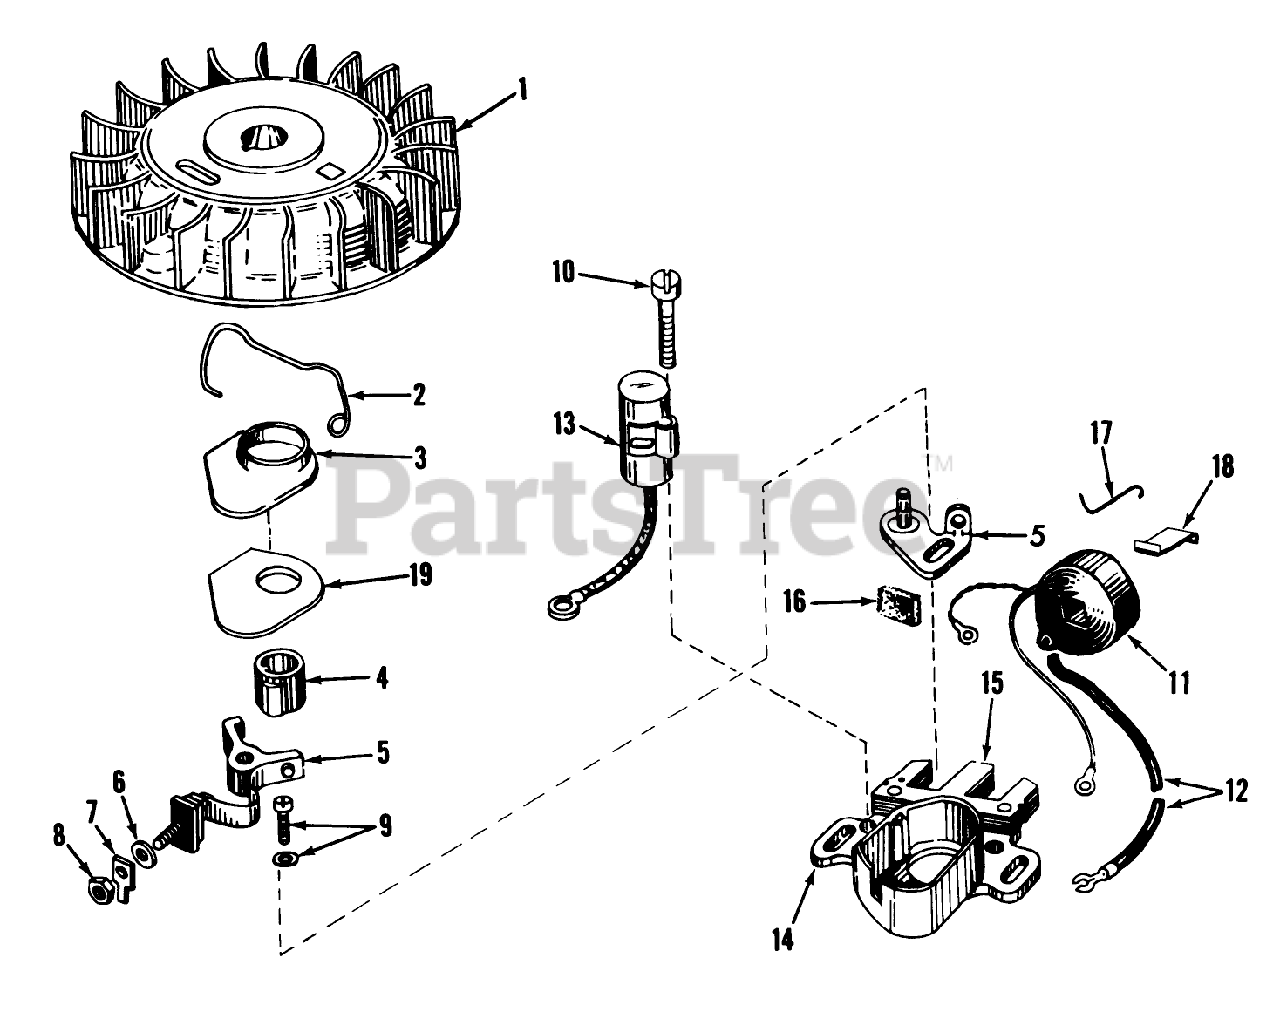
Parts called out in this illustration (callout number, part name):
1	Flywheel
2	Spring Breaker Box
3	Cover, Dust
4	Cam-Breaker
5	Breaker Assy.
6	Washer
7	Terminal
8	DECAL
9	Breaker Screw
10	Condenser Screw
11	Coil Assy. (Incl. No. 12)
12	Wire, Lead
13	Condenser
14	Core Plate
15	Stator Assy., (Incl. Nos. 2, 3, 5 thru 14 16 thru 19)
16	Felt,Cam Wiper
17	Clip, Coil
18	Spring Coil Wedge
19	Gasket, Dust Cover
